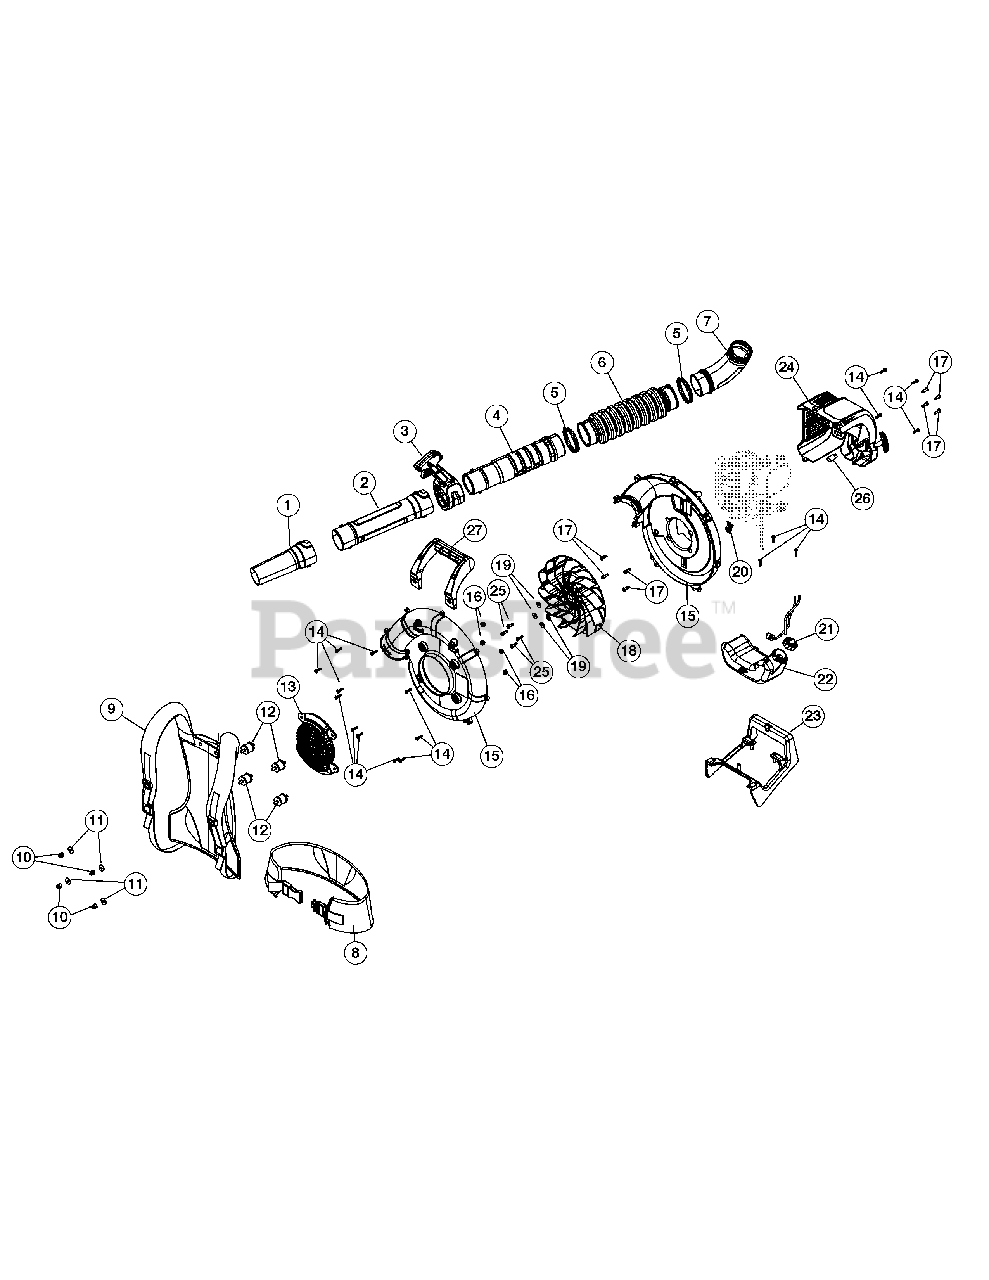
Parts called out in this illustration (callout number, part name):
1	Concentrator Nozzle
2	Lower Blower Tube
3	Throttle Grip Assembly
4	Upper Blower Tube
7	Elbow Tube
9	Support System
10	Nut
11	Washer
12	Isolator Mount
13	Intake Cover
15	Impeller Housing Assembly
17	Housing Screw
18	Impeller
20	Throttle Retaining Clip
22	Fuel Tank Assembly
24	Engine Cover Assembly
25	Impeller Screw
26	Electric Starter Adapter
